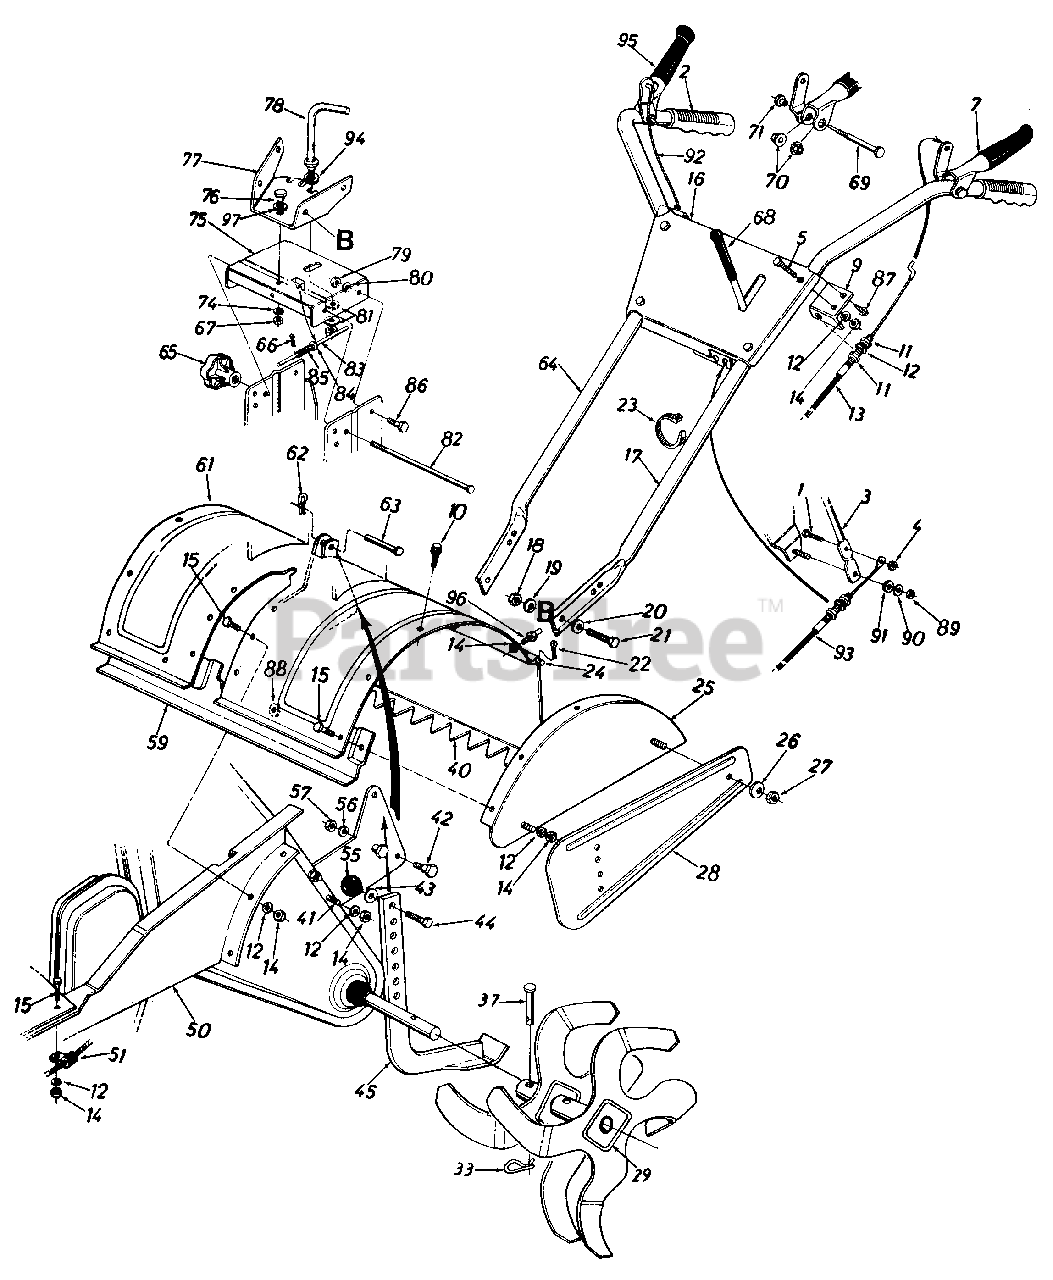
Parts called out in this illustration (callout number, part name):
1	Hex Bolt 1/4-28 x .75" Lg
2	Grip
3	Clutch Lever
4	Hex Cent. L-Nut 1/4-28 Thd.
5	Carr. Bolt 5/16-18 x 1.75"
7	Clutch Grip Ass'y. - L.H.
9	Clutch Cable Bracket
10	Hex Wash. S-Tap Scr. 5/16-18 x .62" Lg.
11	Hex Nut 5/16-24 Thd.
12	L-Wash. 5/16" I.D.
13	Clutch Control Cable (Tines)
14	Hex Nut 5/16-18 Thd.
15	Hex Bolt 5/16-18 x .75" Lg.
19	L-Wash. 3/8" I.D.
20	Bell-Wash. 3/8" I.D.
21	Hex Bolt 3/8-16 x 1" Lg.
22	Cotter Pin 3/32" Dia. x 3/4"
23	Cable Tie
24	Tiller Flap Rod
27	Hex Nut 5/16-18 Thd.
33	Hairpin Cotter
37	Clevis Pin 3/8" Dia.
41	Hex Bolt 5/16-18 x 1.0" Lg.
42	Shld. Bolt 1/2" Dia. x .43"
43	Fl-Wash. 3/8" I.D. x 5/8" O.D.
44	Hex Bolt 3/8-16 x 3/4" Lg.
55	Ball Knob 1-1/4" Dia.
56	L-Wash. 3/8" I.D.
57	Hex Nut 3/8-16 Thd.
63	Clevis Pin 3/8" Dia.
66	Cotter Pin 1/16" Dia. x .75"
67	Hex Cent. L-Nut 3/8-16 Thd.
69	Shoulder Bolt .375" Dia. x 1.37" Lg.
70	Hex Flange Plastic Bearing
71	Shoulder Nut 1/4-20 Thd.
74	Bell-Wash. 40" I.D. x 1.13"
79	Hex Cent. L-Nut 3/8-16 Thd.
80	Bell-Wash. .40" I.D. x .88"
81	Bell-Wash. 1/2" I.D. x 1.00"
82	Lock Pin 5/16" Dia. x 8"
83	Lower Sliding Ass'y.
84	Fl.-Wash. .291" I.D. x .62"
85	Compression Spring 1" Lg.
86	Shoulder Bolt 1/2" Dia. x .170" Lg.
87	Hex Wash. S-Tap Scr. 1/4-20 x .50" Lg.
88	Bell-Wash. 5/16" I.D.
89	Hex Cent. L-Nut 5/16-18 Thd.
90	Fl-Wash. .344" I.D. x .87"
91	rubber Wash. 33 I.D. x .87"
92	Control Cable (Forward)
93	Control Cable (Reverse)
94	Fl-Wash. .62" I.D. x 1.57"
95	Clutch Grip Ass'y. - R.H.
96	Hex Bolt 5/16-18 Thd. (Special)
97	Fl-Wash. .64" I.D. x .94"
